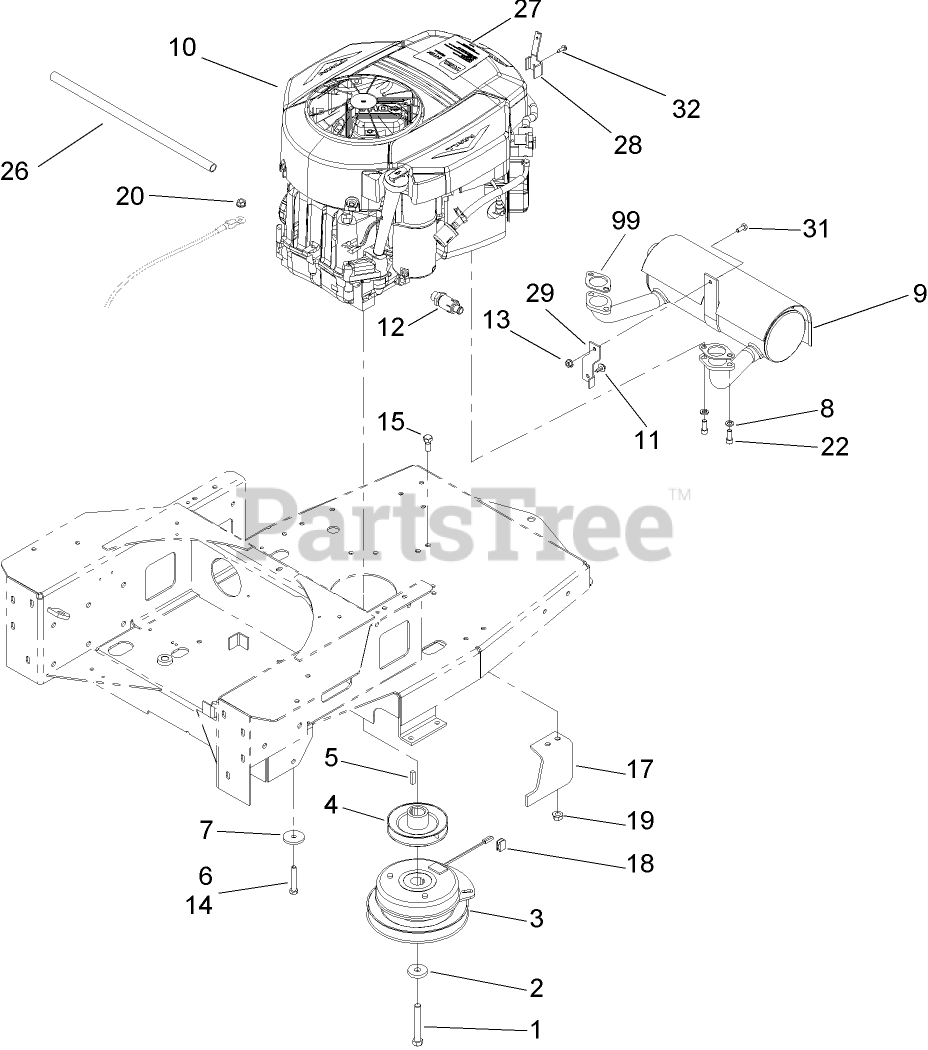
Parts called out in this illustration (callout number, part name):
1	SCREW-HH
2	WASHER
3	CLUTCH-PTO, ELECTRIC
4	PUMP DRIVE PULLEY ASM
6	SCREW-HH
7	SPACER-STEEL
8	WASHER-LOCK
9	MUFFLER
10	Loose Parts Package
11	SCREW-HHFTF
12	VALVE-DRAIN, OIL
13	NUT-HF
14	SCREW-HH
15	SCREW-HH
17	STOP-CLUTCH
18	BUMPER
19	NUT-HF
20	NUT-HF
22	SCREW-HSH
26	TUBE-DRAIN, OIL
27	DECAL-ENGINE (656CC INTEK B&S)
28	BRACKET-CABLE, THROTTLE
29	BRACKET MUFFLER
31	SCREW-HH
32	SCREW-SHWH
99	GASKET-EXHAUST
